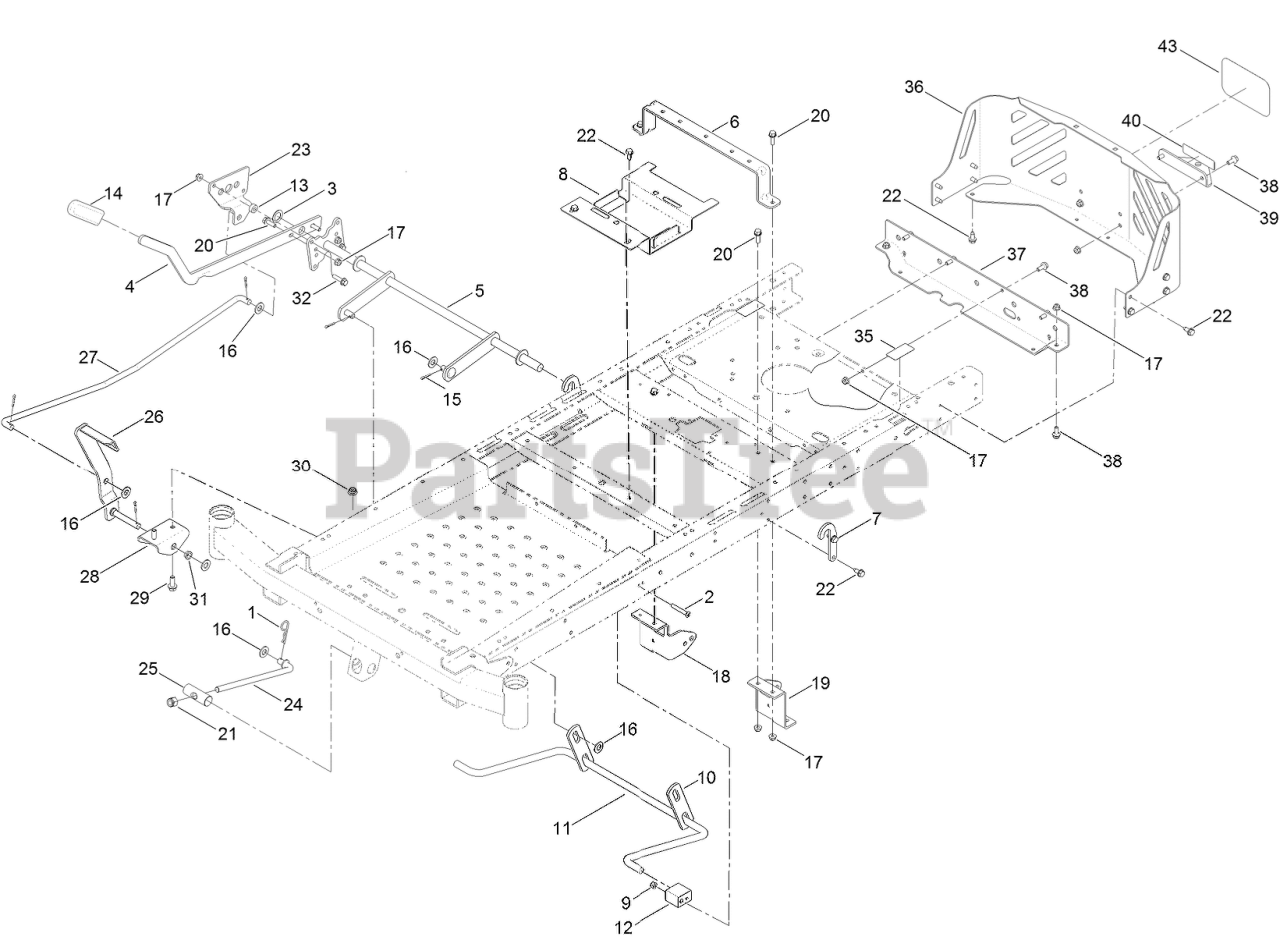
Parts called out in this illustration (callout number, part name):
1	PIN-COTTER
2	SCREW-HSBH
3	WASHER-THRUST
4	LEVER-LIFT
5	LIFT-DECK, WIDE
6	BRACE-SEAT, REAR
7	BRACKET-LIFT
8	BRACKET-BATTERY
9	NUT-LOCK, NI
10	LINK-LIFT
11	ARM-LIFT, REAR (WIDE)
12	BLOCK-PIVOT
13	SPACER
14	GRIP-LEVER
15	PIN-COTTER
16	WASHER-FLAT
17	NUT-HF, NI
18	MOUNT-HYDRO, FRONT (RH)
19	MOUNT-HYDRO, FRONT (LH)
20	SCREW-HHF
21	NUT-HEX
22	SCREW-HWHTF
23	PLATE-FOOTLIFT
24	ROD-MOUNT, DECK
25	PIN-PIVOT
26	PEDAL ASM
27	ROD-FOOTLIFT
28	BRACKET-FOOTLIFT
29	SCREW-HHF
30	NUT-HF, NI
31	BUSHING-FLANGE
32	SCREW-HHF
35	DECAL-BYPASS
36	GUARD-ENGINE, WIDE
37	CROSSMEMBER-REAR, WIDE
38	SCREW-HHF
39	BRACKET-HITCH
43	DECAL
